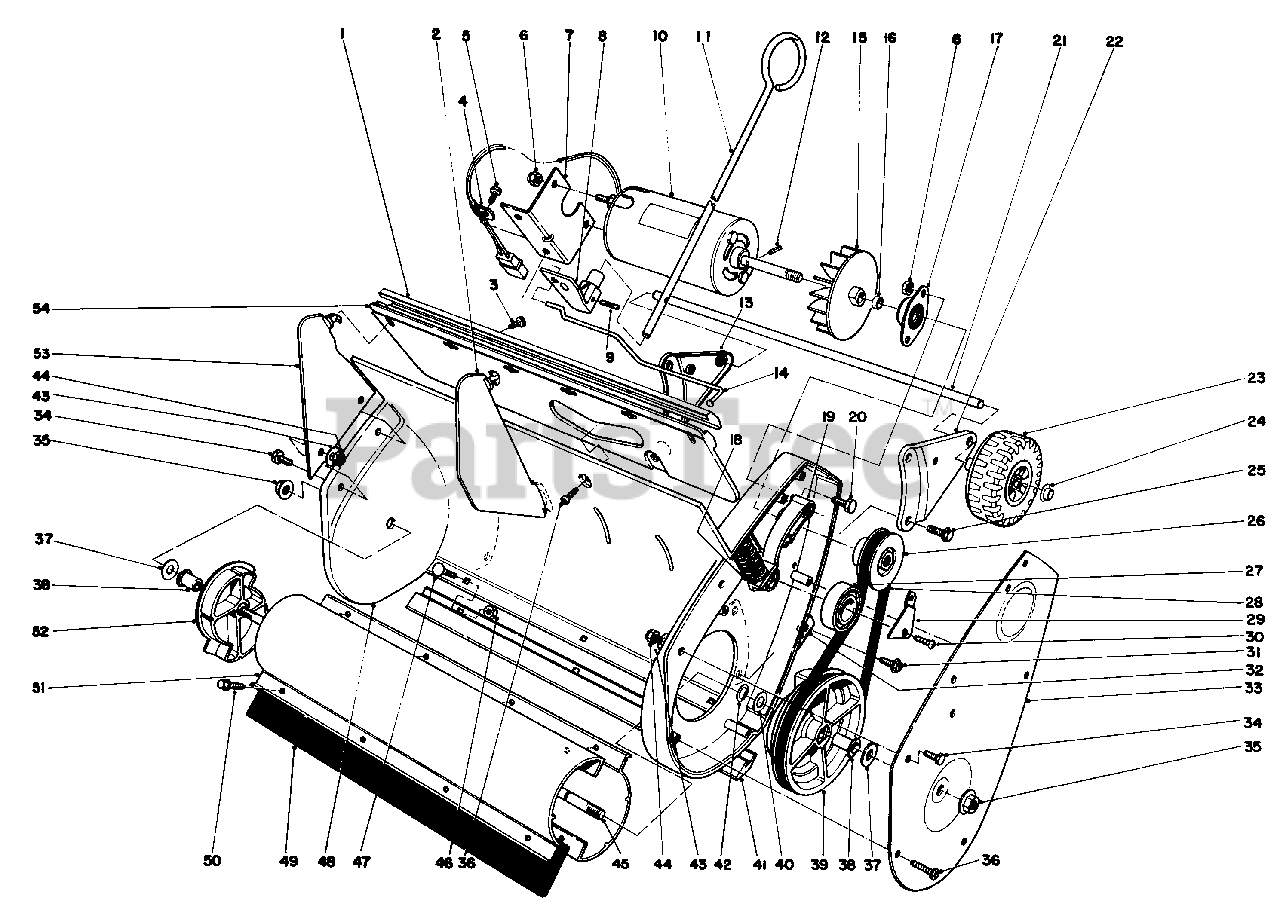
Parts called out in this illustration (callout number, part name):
1	Moulding
2	Vane-Inner
4	Insulated Closed Clip
7	Bracket-Mounting
8	Bracket-Vane Adjustment
9	Groove Pin
11	Rod-Vane Adjustment
12	Spring Pin
13	Wheel Bracket R.H.
14	Linkage Vane Adjustment
17	Bearing-Flanged
18	Idler Spring
19	Idler Arm
21	Axle Shaft
22	Wheel Bracket L.H.
24	Push Nut
25	Screw
26	Drive Pulley
27	Ball Bearing
28	Drive Belt
29	Retainer-Idler Pulley
32	Tinnerman Nut
33	Cover-Belt Case
36	Screw
37	Thrust Washer
38	Rotor Bushing
39	Pulley-Driven
40	Thrust Washer
42	Retaining Ring
43	Washer
45	Shaft-Rotor
47	Carriage Bolt
49	Blade-Rotor
50	Screw-Thread Forming
52	End Cap Rotor
53	Vane-Outer
54	Vane-Mount
